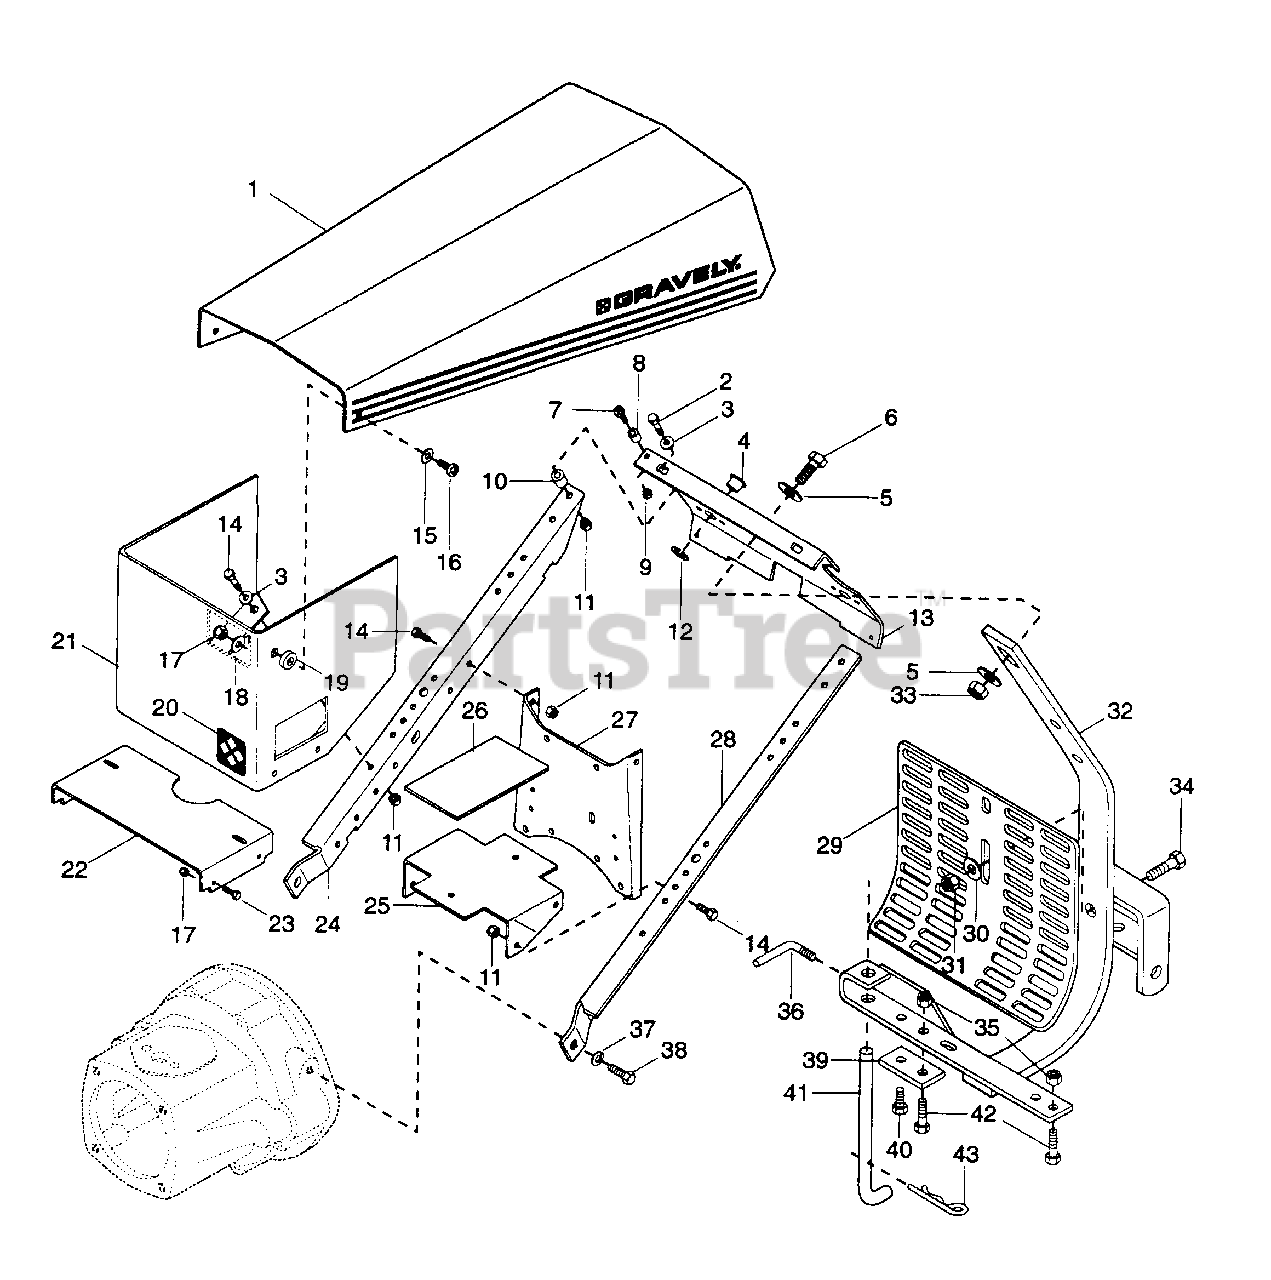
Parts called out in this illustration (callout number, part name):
1	HOOD SILK SCREEN
2	BLT-HEX .38-16 X 1.50 PL GR 5
3	WSHR-FL-STL .406 X .812 X .065 PL
4	BUSH-FLG .515 X 1.00 X .745 NY
5	WSHR-FL-STL .656 X 1.25 X .100
6	BLT-HEX .625-11 X 2.00
7	SCR-MCH 6-32 X .625
8	BUMPER
9	NUT-LK-MCH 6-32 W/INSERT
10	BUSHING
11	NUT-LK-NYL .375-16 PL
12	RG-RTNG 1.000 X .748
13	PLT, SILK SCREEN
14	BLT-HEX .380-16 X .875
15	WSHR-FL-STL .281 X .62 X .065 PL
16	SCR-MCH .50-20 X 1
17	NUT-LK-NYL .250-20 PL
18	WSHR-FL-STL .313 X .875 X .065
19	BUSH., F .280 X .750 X .318 NY
20	DECAL, COM. FRONT
21	SPRT, HOOD
22	BRKT
23	BLT-HEX .25-20 X .63
24	SPRT, HANDLE BAR R.H.
25	BRKT, TANK SUPPORT
26	PAD, GAS TANK
27	BRKT
28	SPRT, HANDLE BAR L.H.
29	GRD, ENGINE
30	WSHR-FL-STL .531 X 1.25 X .100
31	NUT-LK-NYL .50-13 PL
32	WLDMT, HITCH
33	NUT-LK-NYL .625-11 PL
34	BLT-HEX .50-13 X 1.50 PL GR 5
35	NUT-LK-NYL .312-18 PL
36	HNDL, ADJUSTING
37	WSHR-LOCK .50 REG.
38	BLT-HEX .50-13 X 1 PL GR 5
39	BRACKET
40	BLT-HEX .31-18 X 1.00 PL GR 5
41	STAND, KICK
42	BLT-HEX .31-18 X 2.00 PL GR 5
43	PIN-HAIR-INT .15 X 2.937
